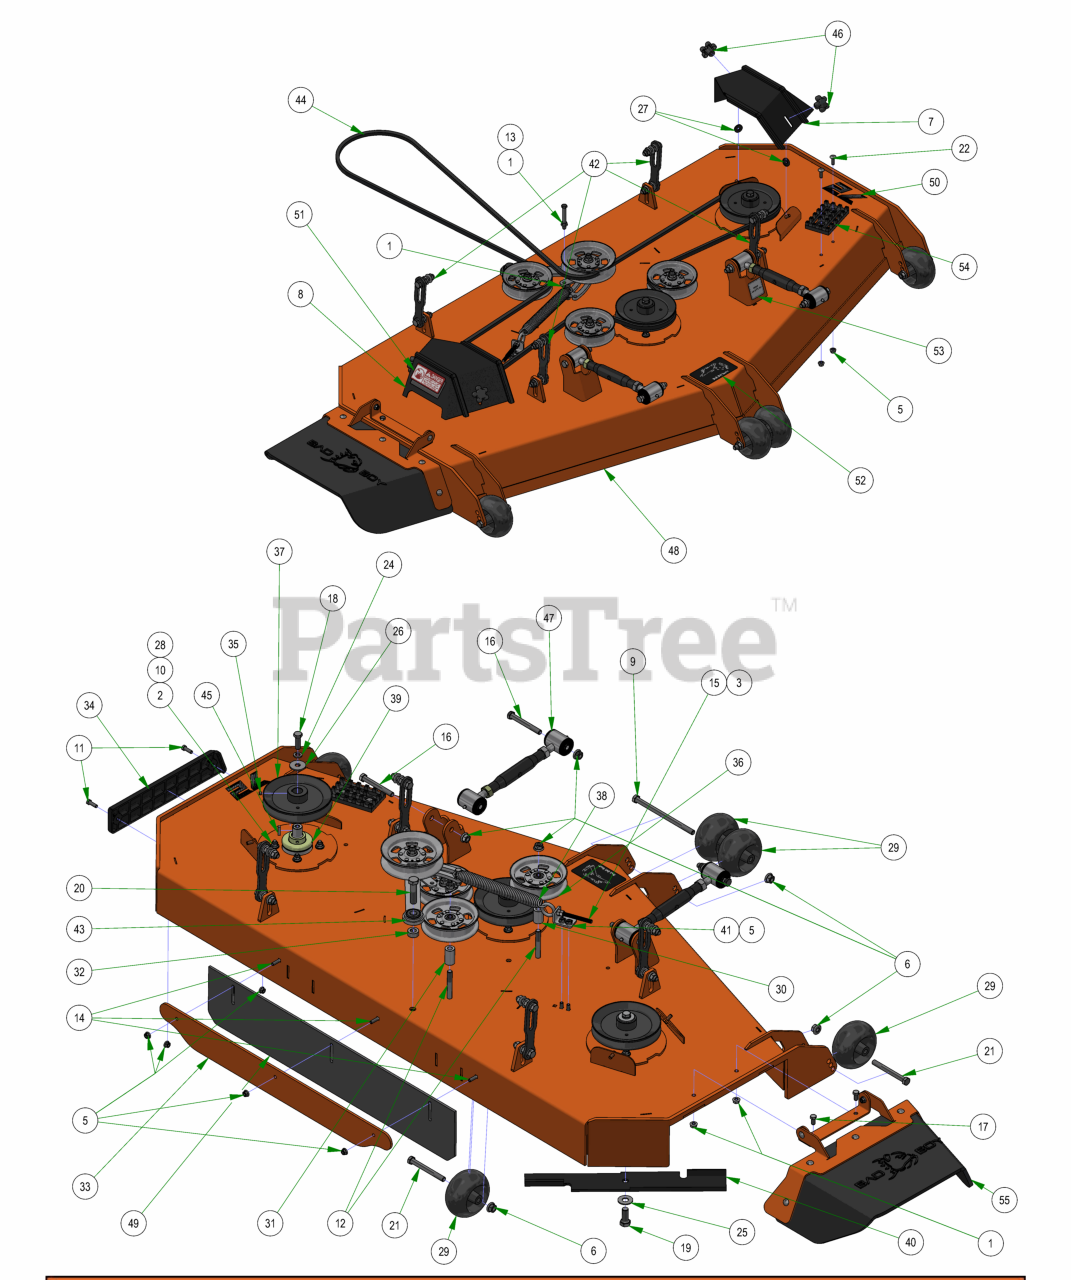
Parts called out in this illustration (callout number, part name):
1	3/8-16 HEX SERRATED FLANGE NUT HARD/ZINC
2	3/8-16 NYLON INSERT FLANGE LOCKNUT (GR.F) ZINC
3	3/8-16 HEX NUT ZINC
4	5/8-11 NYLON INSERT LOCKNUT ZINC
5	5/16-18 NYLON INSERT FLANGE LOCKNUT ZINC
6	1/2-13 NYLON INSERT FLANGE LOCKNUT ZINC
7	2019 72" Left Outlaw Gen2 Pulley Cover
8	2019 72" Right Outlaw Gen2 Pulley Cover
9	1/2-13 X 8 HEX CAP SCREW GR 5 ZINC
10	3/8-16 X 1-3/4 HEX C/S (GR.5) ZC
11	5/16-18 X 1 HEX CAP SCREW (GR.5) ZINC
12	1/2-13 X 3-1/2 HEX FLANGE BOLT (GR.8) ZINC
13	3/8-16 X 3 HEX CAP SCREW (GR.5) ZINC
14	5/16-18 X 1-1/4 CARRIAGE BOLT ZINC
15	4" 3/8-16 Eye Bolt
16	1/2-13 X 4 HEX CAP SCREW (GR.8) ZINC YELLOW
17	3/8-16 X 3/4 HEX CAP SCREW (GR.5) ZINC
18	1/2-20 X 1-1/2 HEX CAP SCREW (GR.5) ZINC
19	5/8-18 X 1-1/2 HEX CAP SCREW (GR.8) ZINC YELLOW
20	5/8-11 X 2-1/2 HEX CAP SCREW (GR.5) ZINC
21	1/2-13 X 4-1/2 HEX CAP SCREW (GR.5) ZINC
22	5/16-18 X 1 CARRIAGE BOLT (GR.8) ZINC
23	5/16-18 X 7/8 CARRIAGE BOLT ZINC
24	1/2 SPLIT LOCKWASHER (GR.8) ZINC/YELLOW
25	5/8 USS FLAT WASHER (1-3/4" OD) GR.8 ZINC YELLOW
26	1/2 BELLEVILLE WASHER (1-5/8 OD X .140 THK) ZINC
27	.360 ID X .983 OD X .120 THICK FLAT WASHER NYLON BLACK
28	5/16 USS FLAT WASHER (7/8 OD) ZINC
29	2019 Deck Wheel
30	.502 ID X .750 OD X 1.500 Long Spacer
31	1 3/4" Pulley Spacer
32	5/8 SOLID SHAFT COLLAR (W/1 SET SCREW) ZINC
33	61 Bolt in Baffle Deck v2 Stripping Plate
34	REVISED TRIM BUMPER_20180226
35	5/16-24 X 1/4 SOCKET SET SCREW (CUP PT) PLAIN
36	5-3/4 Idler Pulley
37	7" Deck Pulley
38	2019 Outlaw Gen2 Deck Spring
39	OUTLAW SPINDLE ASSEMBLY
40	72" High Lift Fusion Blade
41	2019 Deck Eye Bolt Tab
42	Deck Hanger Assembly
43	2019 Renegade Deck Idler
44	Belt for 72" Renegade
45	1/4 X 1 SQ MACHINERY KEY 1018 STL PLN
46	5/16" Knob
47	Turnbuckle Assembly (M20-2.5)
48	2019 Sloped 72" Deck
49	R Series Rubber For Deck
50	72" Deck Decal
51	Danger Decal-Spindle/Discharge
52	2019 Renegade Deck Belt Route Decal
53	Deck Impact Patent Decal 9591803
54	Deck Step Assembly
55	2019 Outlaw Gen2 Chute Assembly
